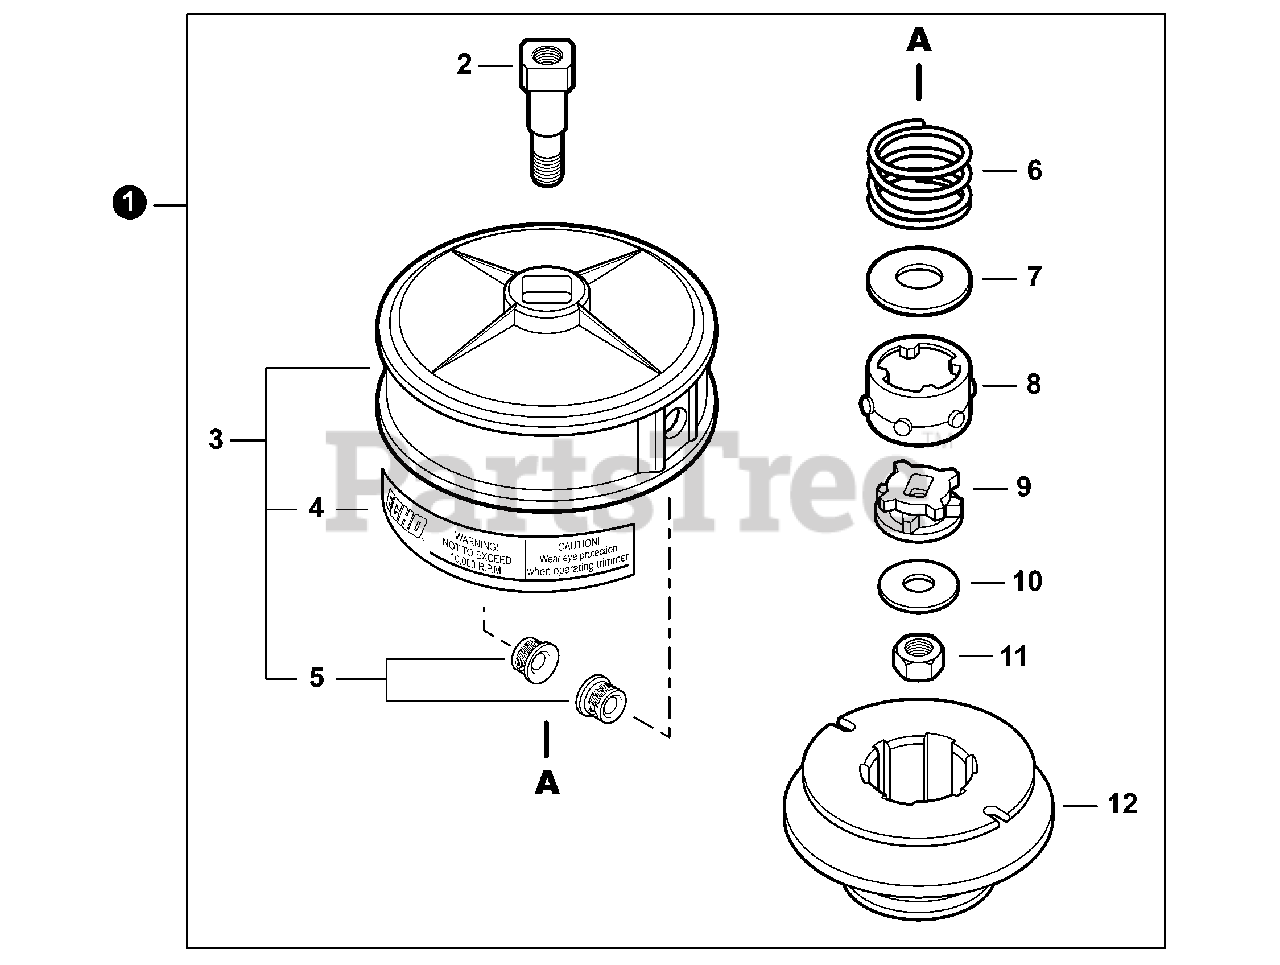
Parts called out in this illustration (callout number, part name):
1	TRIMMER HEAD, SRM ECHOMATIC
2	STUD, ARBOR M10 × 1.25 FLH / 5/16-24 MRH
3	HOUSING ASSY, SPOOL
4	LABEL, CAUTION
5	EYELET
6	SPRING, COMPRESSION
7	WASHER 14
8	CAM, OUTER
9	CAM, INNER
10	WASHER 8
11	NUT, LOCK 8
